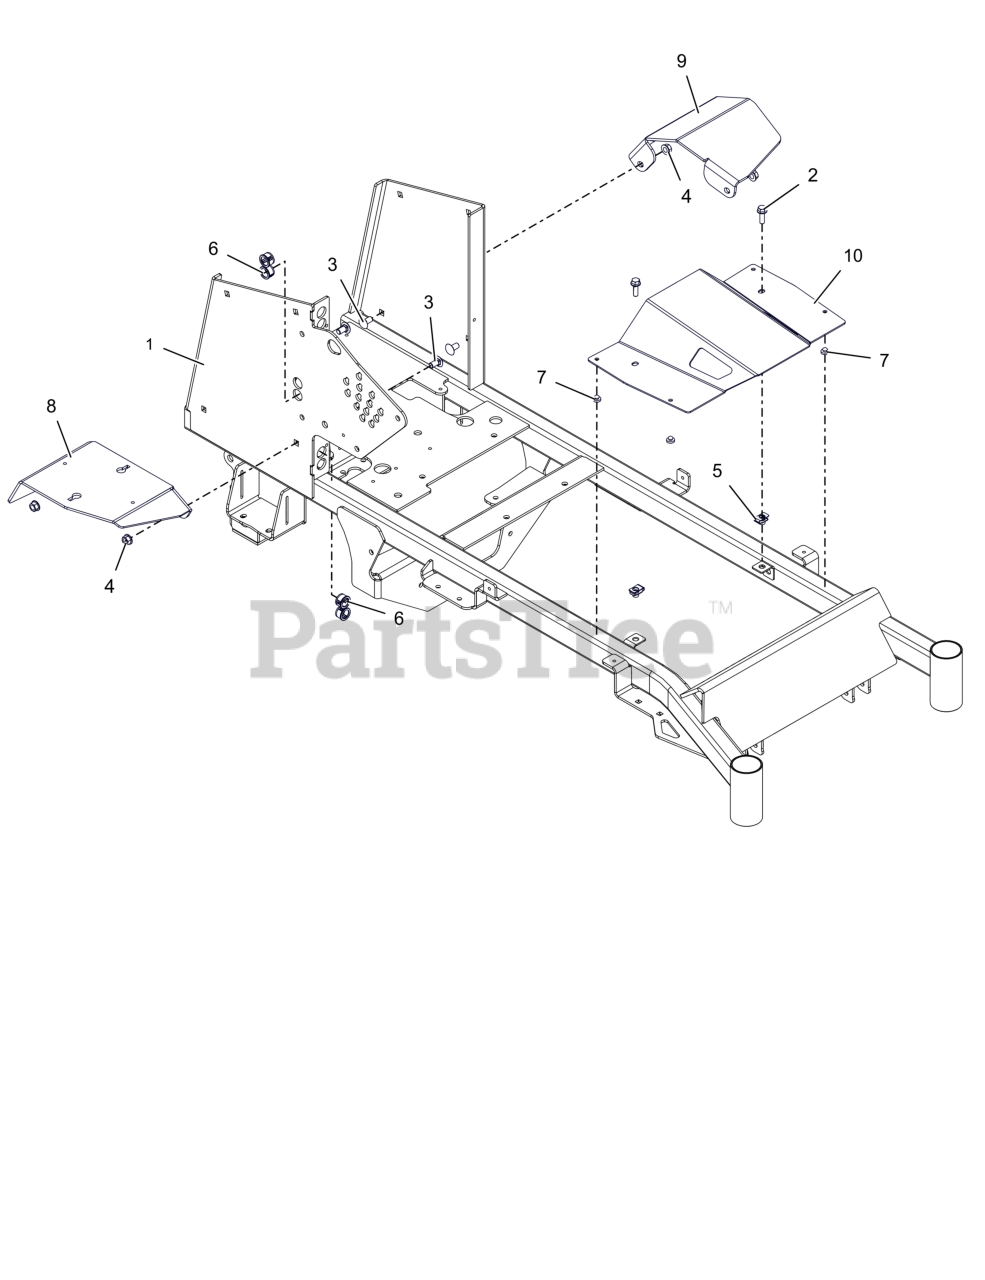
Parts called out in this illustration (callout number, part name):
1	WLDMT, RIDGELINE 32 FRAME (ORANGE)
2	BLT- HEX-FLG .31-18X1.00 ZB500
3	BLT, RHSSN .38-16X.75 G5 ZCC
4	NUT-LK-CTR-FLG .375-16 GF ZCC
5	NUT-CLIP RETAINER 5/16-18X.56
6	BUSH, PANEL SNAP .687X.875X.56
7	BUMPER GROMMET
8	FENDER- RH
9	FENDER- LH
10	COVER, Z-STANCE 32" BELT (ORANGE)
